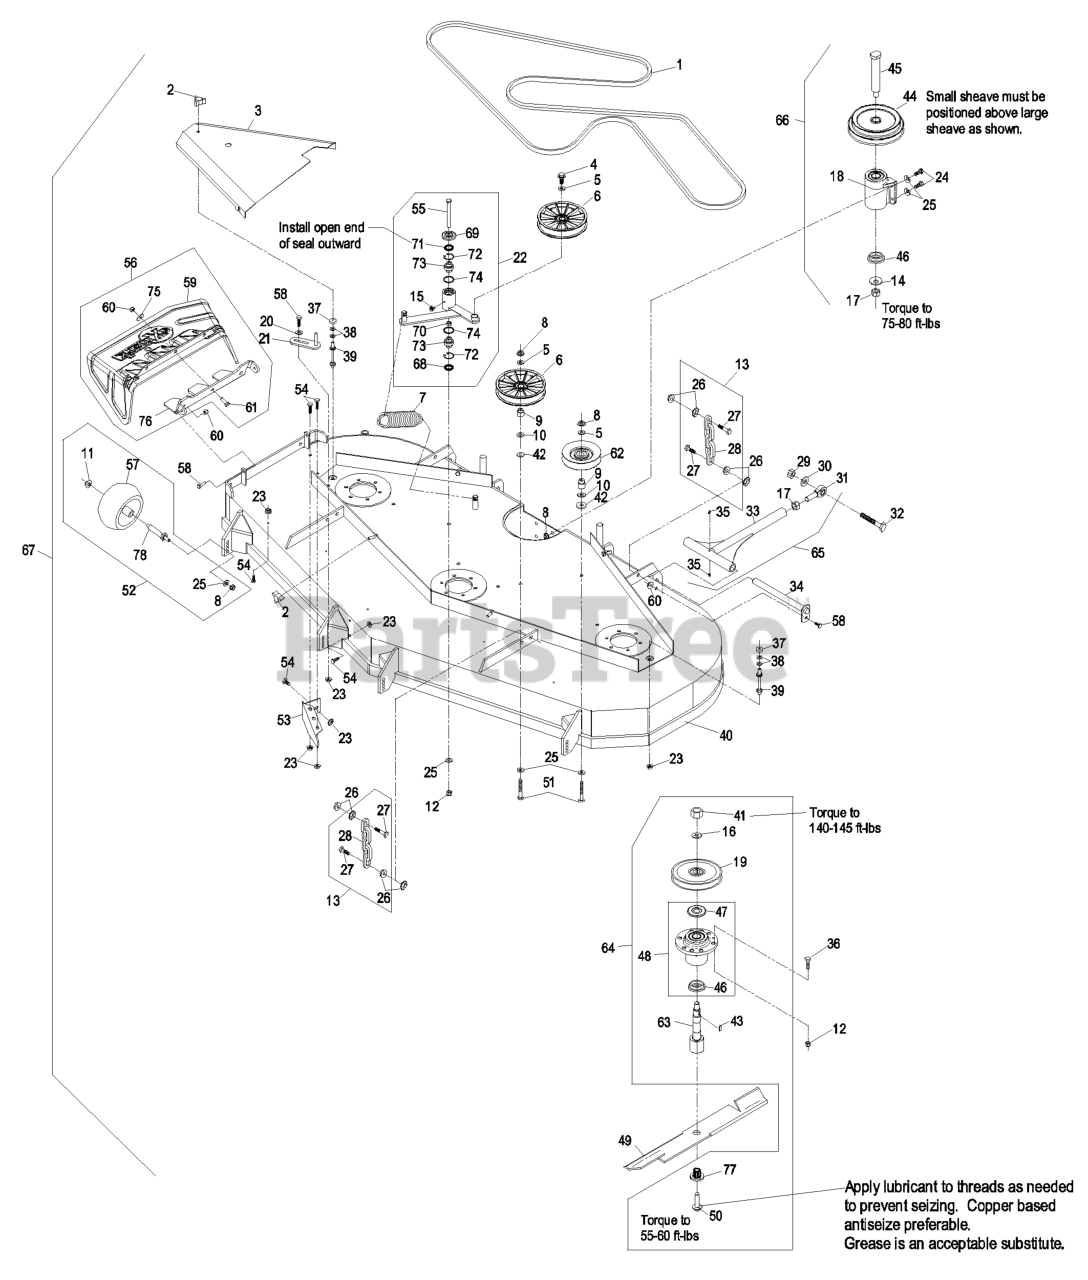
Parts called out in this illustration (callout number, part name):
1	BELT-V
2	KNOB-3 PRONG
3	SHIELD,BELT RH
4	SCREW-HHF
5	WASHER-FLAT
6	PULLEY,IDLER 6"
8	NUT-HHF, WHIZ
9	BUSHING-IDLER
10	WASHER-FLAT
11	Nut-Nyloc 3/8-16 Flg
12	NUT-LOCK, NI
13	DECK CHAIN ASM
14	WASHER-SPRING
15	FITTING-GREASE, 90 DEG
17	NUT-HEX
18	KIT, JACKSHAFT ASSY
19	SHEAVE,BLADE DRIVE 7.5
20	WASHER-SPRING
21	GUIDE-BELT
22	KIT,DECK IDLER LZ/XP
24	SCREW-HH
25	WASHER-BELLEVILLE
27	SCREW-HH
28	CHAIN-LIFT, DECK
29	NUT-HEX
30	WASHER-LOCK
31	BALLJOINT-SPHERICAL
32	SCREW-HH
33	WLD,DECK STRUT-72"
34	PIN-STRUT
35	FITTING-GREASE
36	SCREW-HH
38	WASHER-FLAT
39	STUD-SHIELD, BELT (SHORT)
44	SHEAVE, JACKSHAFT DOUBLE
45	JACKSHAFT
46	SPACER-GUARD, BOTTOM
47	GUARD-BEARING, TOP
48	KIT, CUTTER HOUSING
51	BOLT-CARR
53	WLD,BAFFLE DISCHARGE
54	SCREW-HH
55	SCREW-HH
57	ROLLER-SCALP, ANTI
58	SCREW-HH
59	CHUTE,DISCHARGE
60	NUT-LOCK, NI
61	SCREW-CARR
62	PULLEY-IDLER
63	KIT, SPLINED SPINDLE 103-
64	ASM, CUTTER HSG COMP 72
65	ASM,STRUT 72 LONG
66	KIT,JACKSHAFT 60/72-3750
67	Complete Deck Asm
68	SEAL-LIP, DOUBLE
69	GUARD-TOP
71	SEAL-LIP, SINGLE
72	RING-SNAP
73	BEARING-SPHERICAL
75	WASHER-FLAT
76	BRACKET,DISCHARGE CHUTE
77	BUSHING,SPLINED
